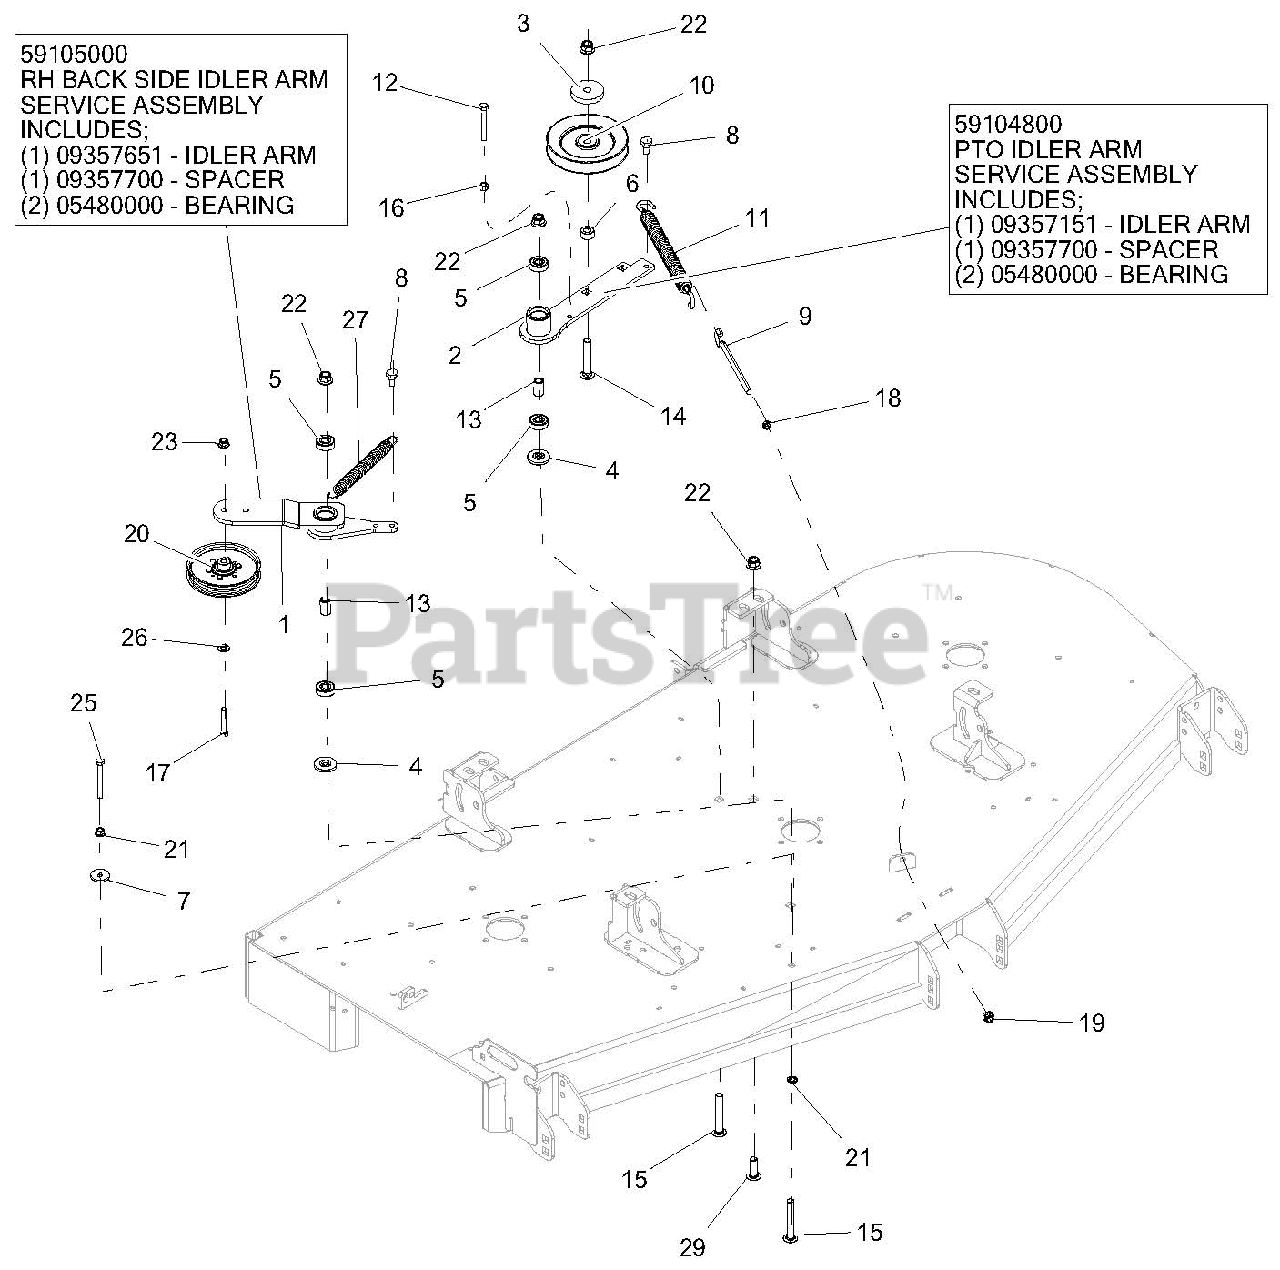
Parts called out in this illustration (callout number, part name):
1	WLDMT, DECK RH IDLER ARM
1	RH BACK SIDE IDLER ARM SERVICE ASSEMBLY
1	IDLER ARM
1	SPACER
1	BEARING
2	WLDMT, DECK PTO IDLER ARM-BLACK
2	PTO IDLER ARM SERVICE ASSEMBLY
2	IDLER ARM
2	SPACER
2	BEARING
3	CAP, IDLER BEARING SEALING
4	SPACER, IDLER ARM
5	BRG-BALL .500X1.375X.44
6	BSHG, SPCR .502 X .997.50 PM
7	WSHR-FL-STL .406X1.375X.135 YZ
8	BLT, SHLDR EP .38-16X.30 HEX YZ
9	BOLT, .38-16X6.00 .62 DIA EYE
10	SHEAVE, .50" ID X 6.00" OD V-IDLER
11	SPRG, EXTENSION
12	BLT-HEX .38-16X2.75 GR5 YWZC
13	SPACER, .510 X .750 X 1.148
14	BLT-RDHDSQNK .50-13X3.00YG5
15	BLT-RDHDSQSHNK .50-13X3.25 YWZC
16	NUT-HEX .38-16 YWZC
17	BLT-HEX .38-16X2.00 GR5 YWZC
18	NUT, JAM .375-16 YWZC
19	NUT-LK-NYL-FLG .38-16 YWZC
20	PULLEY, FLAT IDLER .500 X .375 W/BRG
21	@NUT-SPNLK-FLG .375-16 YWZC
22	NUT-LK-NYL-FLG .50-13 YWZC
23	NUT-LK-NYL-FLG .38-16 YWZC
25	BLT-HEX .38-16X3.00 GR5 YWZC
26	WSHR-FL-STL.406X.812X.065 YWZ
27	SPRG, EXTENSION .120X.845X6.55 WLD
29	BLT-RDHDSQSHNK .50-13X1.50 YWZC
